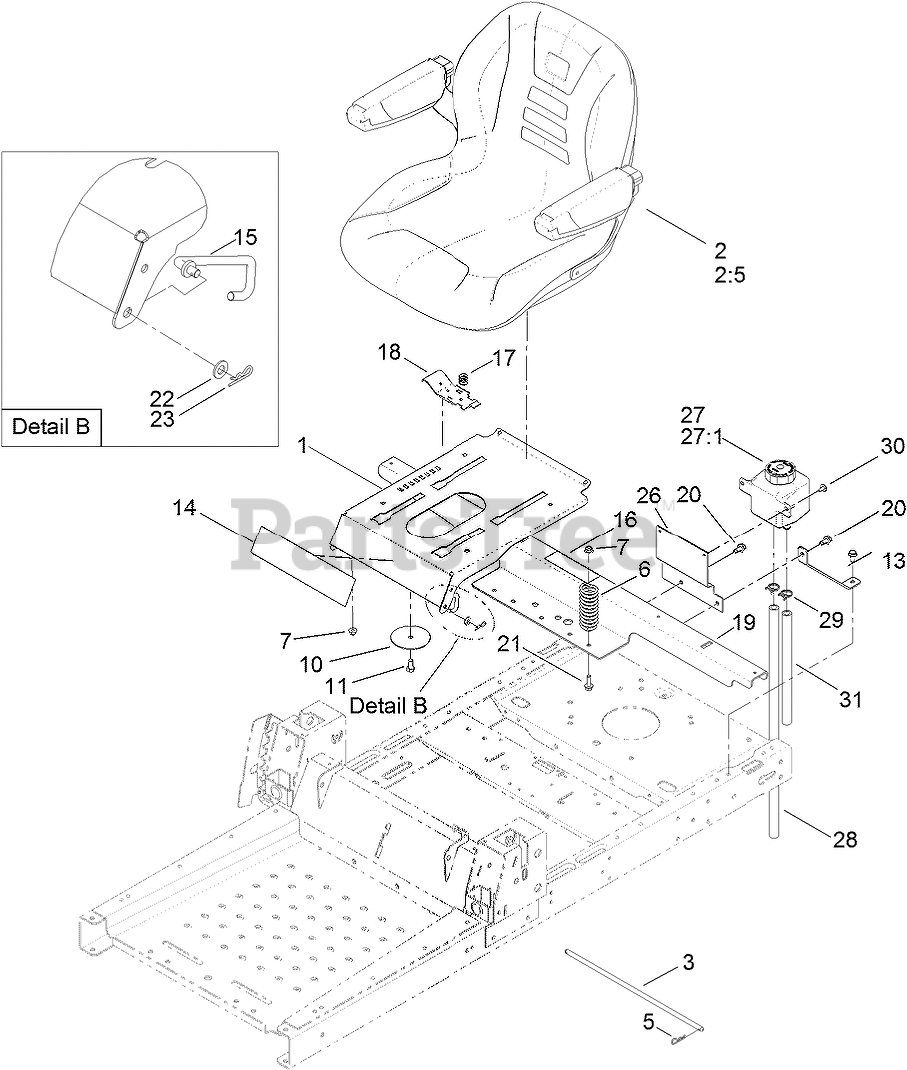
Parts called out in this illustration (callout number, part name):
1	PAN-SEAT
2	18 INCH SEAT ASM
2:5	ARMREST KIT
3	ROD-STOP
5	PIN-COTTER
6	SPRING-COMPRESSION
7	NUT-HF, NI
10	WASHER-SEAT
11	SCREW-HH
13	SUPPORT-TANK, REAR
15	STOP-SEAT
16	DECAL-SERVICE, CE
17	SPRING-COMPRESSION
18	LATCH-SEAT
19	SUPPORT-POD
20	SCREW-HWHTF
21	SCREW-HHF
22	WASHER-PLAIN
23	PIN-COTTER
26	MOUNT-TANK
27	VENT-TANK, HYD
27:1	CAP-RESERVOIR, HYD
28	HOSE-OVERFLOW
29	CLAMP-HOSE
30	SCREW-HHFTF
31	HOSE-OVERFLOW
